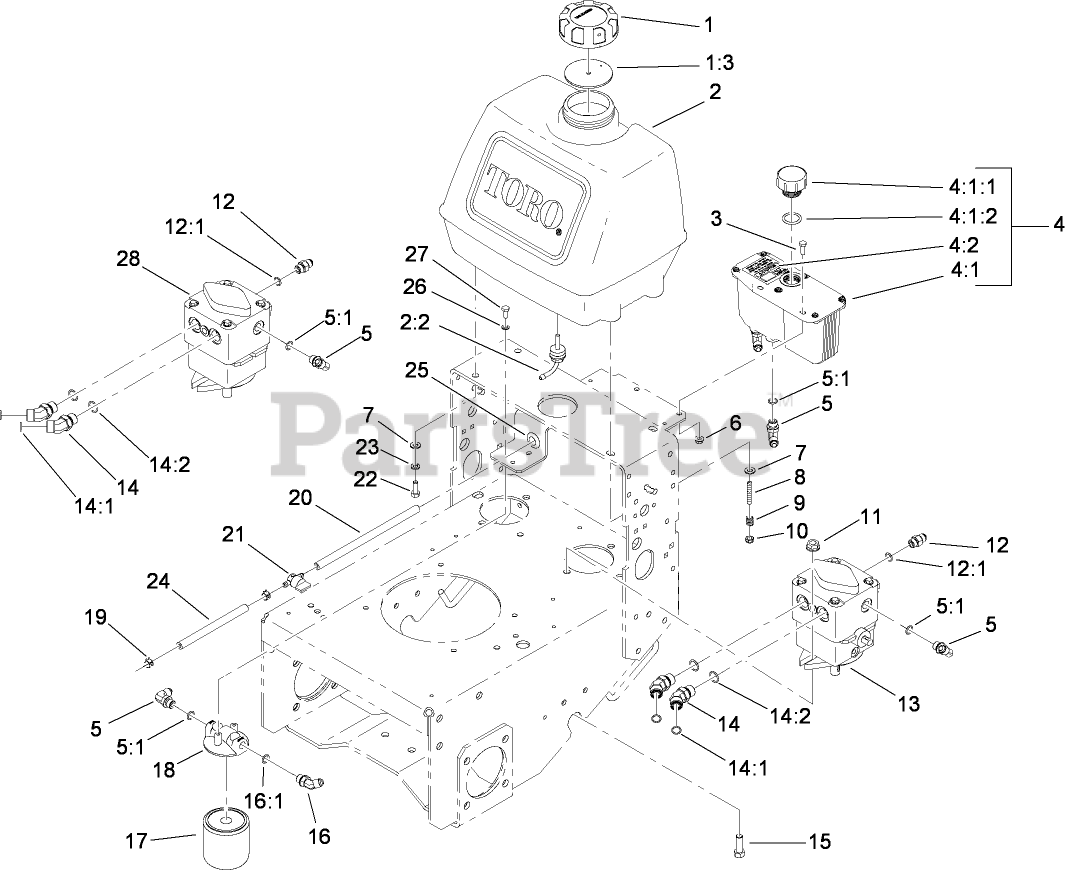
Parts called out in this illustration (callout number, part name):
1	GAS CAP ASM
1:3	GASKET-CAP, GAS
2	FUEL TANK ASM
2:2	FITTING-FUEL, BULKHEAD
3	SCREW-HH
4	HYD Reservoir ASM
4:1	Reservoir-HYD
4:1:1	CAP-RESERVOIR, HYD
4:1:2	GASKET-CAP
4:2	DECAL-TANK, HYD
5	FITTING-ELBOW, 90 DEG
5:1	O-RING
6	NUT-HF
7	WASHER-PLAIN
8	STUD-THREADED
9	SPRING-TANK, FUEL
10	NUT-LOCK, NI
11	NUT-HF
12	FITTING-STRAIGHT
12:1	O-RING
13	PUMP-HYD
14	FITTING-HYD, 45 DEG
14:1	O-RING
14:2	O-RING
15	SCREW-HH
16	FITTING-ELBOW, 45 DEG
16:1	O-RING
17	FILTER-OIL, HYD
17	FILTER-OIL, HYD (WINTER)
18	HEAD-FILTER
19	CLAMP-HOSE
20	HOSE-FUEL
21	VALVE-FUEL
22	SCREW-HH
23	WASHER-LOCK
24	HOSE-FUEL
25	GROMMET
26	WASHER-LOCK
27	SCREW-HH
28	PUMP-HYD
